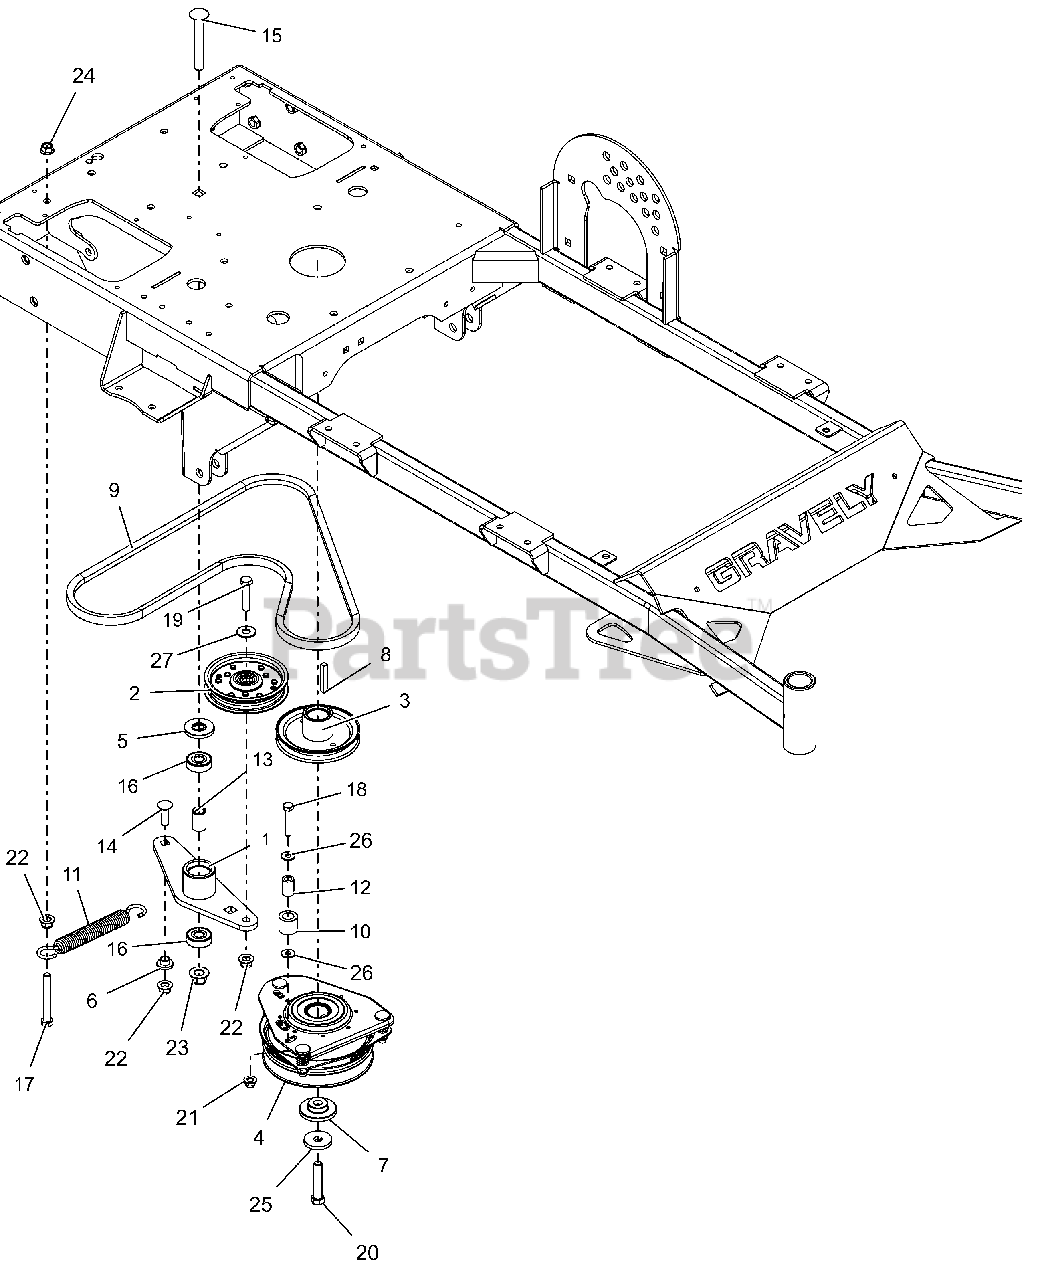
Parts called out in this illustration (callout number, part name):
1	WLDMT, PRO WALK IDLER ARM (BLACK)
2	ASM, 4" IDLER (.75 WIDE)
3	SHEAVE, ENGINE 4.50 x 1.004 ID (BLACK)
4	CLUTCH, OGURA GT1A-AR03
5	SPACER, IDLER ARM
6	BSHG-FLG .385X.500X.875X.406
7	BSHG-FLG .469X1.06X.574X2.0
8	KEY-STR .25X1.75X.25
9	V-BELT, HA WRAPPED
10	BUMPER,RUBBER .62X1.0X.88 LG
11	SPRING, EXTENSION
12	BUSH.,S.391X.622X.950 ST
13	SPACER .510 X .75 X 1.1485
14	@BLT-RDHDSQNK .38-16X1.25 G5YZ
15	@BLT-RHDSSQNK .50-13X3.50 G5YZ
16	BRG-BALL .500X1.38X.437
17	@BLT-HEX .38-16X3.00 GR5 YWZC
18	@BLT-HEX .31-18X1.75 GR5 YWZC
19	@BLT-HEX .38-16X1.75 GR5 YWZC
20	BLT-HEX .44-20X2.25 G8YZNYTORQ
21	@NUT-LK-NYL-FLG .31-18 YWZC
22	@NUT-LK-NYL-FLG .38-16 YWZC
23	@NUT-LK-NYL-FLG .50-13 YWZC
24	@NUT-SPNLK-FLG .375-16 YWZC
25	WASHER, 7/16" SPRING DISK
26	@WSHR-FL-STL.312X.734X.065 YWZ
27	@WSHR-FL-STL.438X1.00X.083 YWZ
